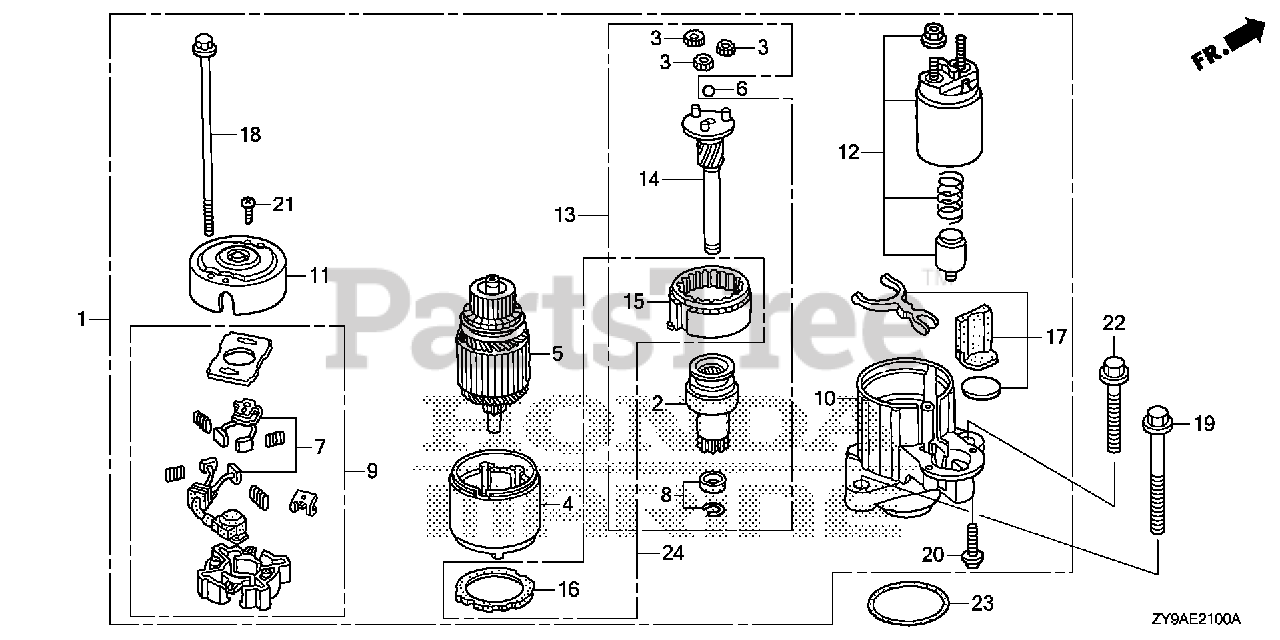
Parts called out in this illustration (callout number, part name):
1	STARTER MOTOR ASSY.
2	CLUTCH, OVERRUNNING
3	GEAR ASSY., PLANETARY
6	BALL, STEEL
8	STOPPER SET, SLEEVE
9	HOLDER, BRUSH
10	BRACKET, FR.
11	BRACKET, RR.
12	SWITCH ASSY., MAGNET
13	SHAFT ASSY., CLUTCH
14	SHAFT ASSY., GEAR
18	BOLT A, THROUGH
19	BOLT, FLANGE (10X75)
20	SCREW, PAN (6X22)
21	SCREW, PAN (5X8)
22	BOLT, FLANGE (10X35)
23	O-RING (59.4X3.1)
24	GEAR ASSY. (INNER)
